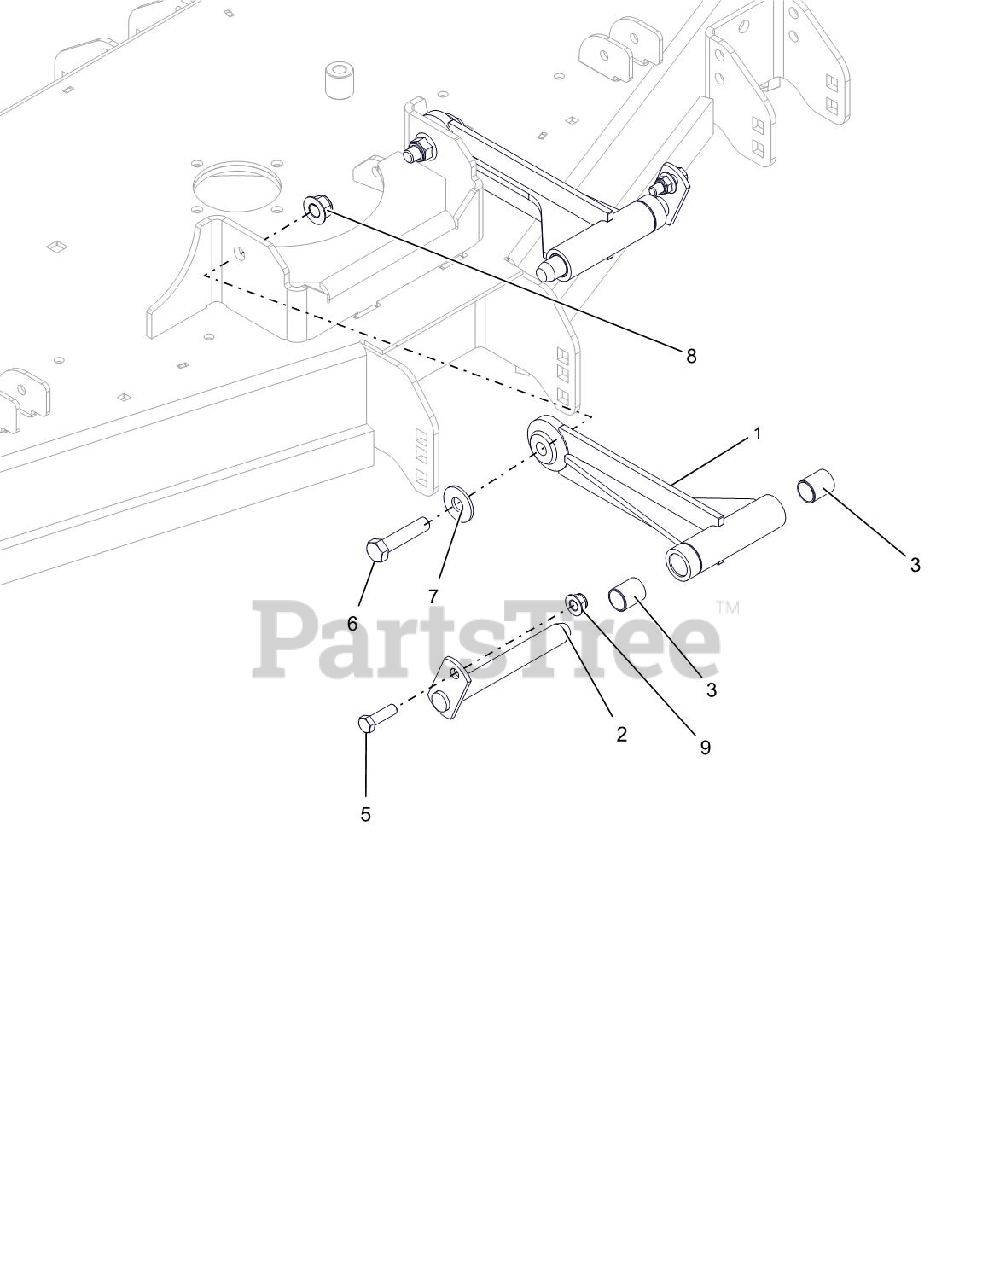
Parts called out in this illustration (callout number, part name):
1	WMT, DRAG LINK
2	WELDMENT, MOWER MTG. PIN
3	BRG, .750 X .875 X 1.000
5	@BLT-HEX .38-16X1.25 GR5 YWZC
6	@BLT-HEX .50-13X2.25 GR5 YWZC
7	@WSHR-FL-STL.563X1.38X.109YWZC
8	@NUT-LK-NYL-FLG .50-13 YWZC
9	@NUT-LK-NYL-FLG .38-16 YWZC
